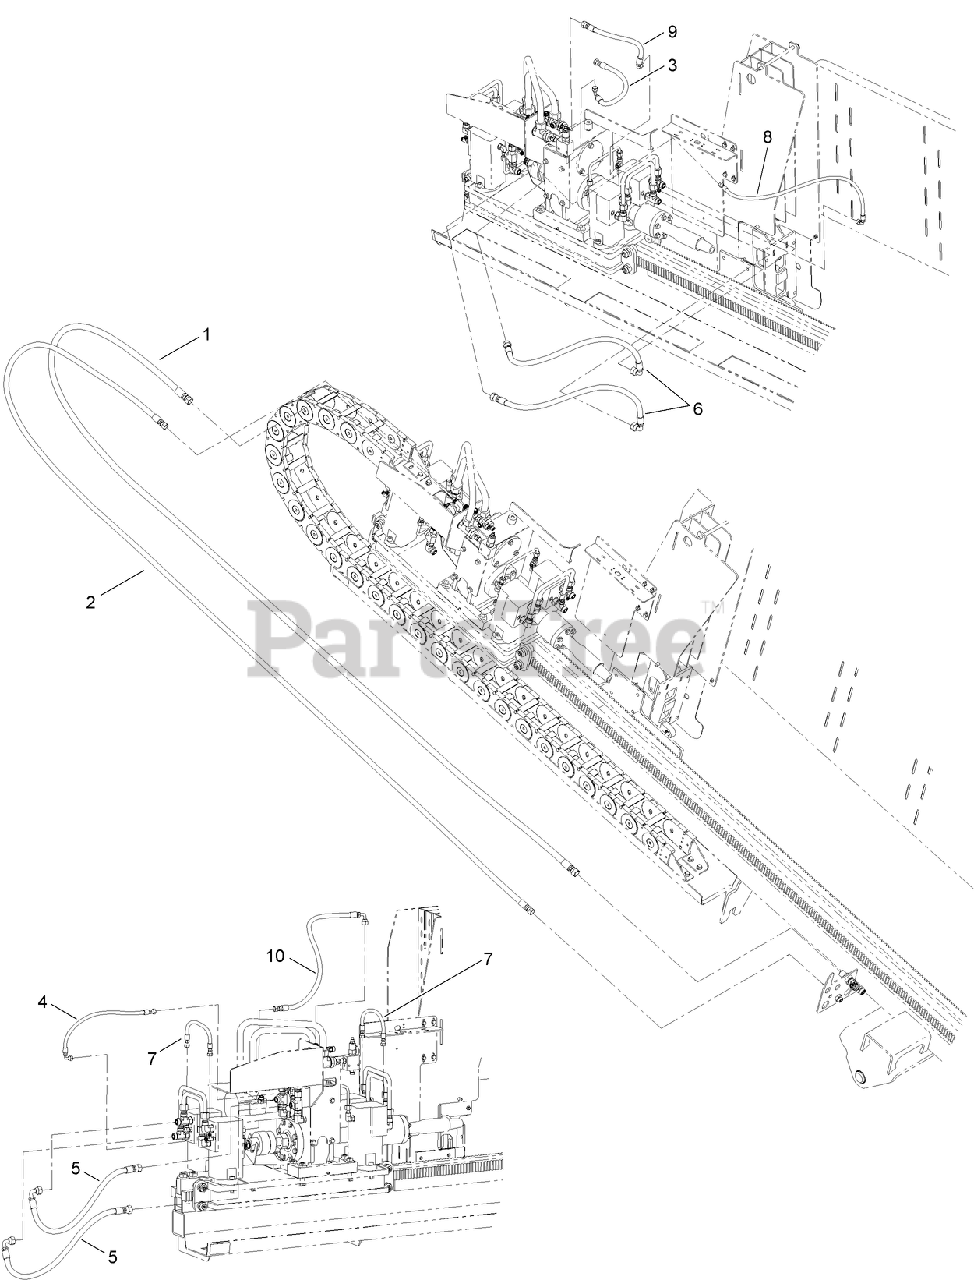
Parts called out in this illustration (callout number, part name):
1	HOSE ASM
2	HOSE ASM
3	HOSE ASM
4	HOSE ASM
5	HOSE ASM
6	HOSE ASM
7	HOSE ASM
8	HOSE ASM
9	HOSE ASM
10	HOSE ASM
